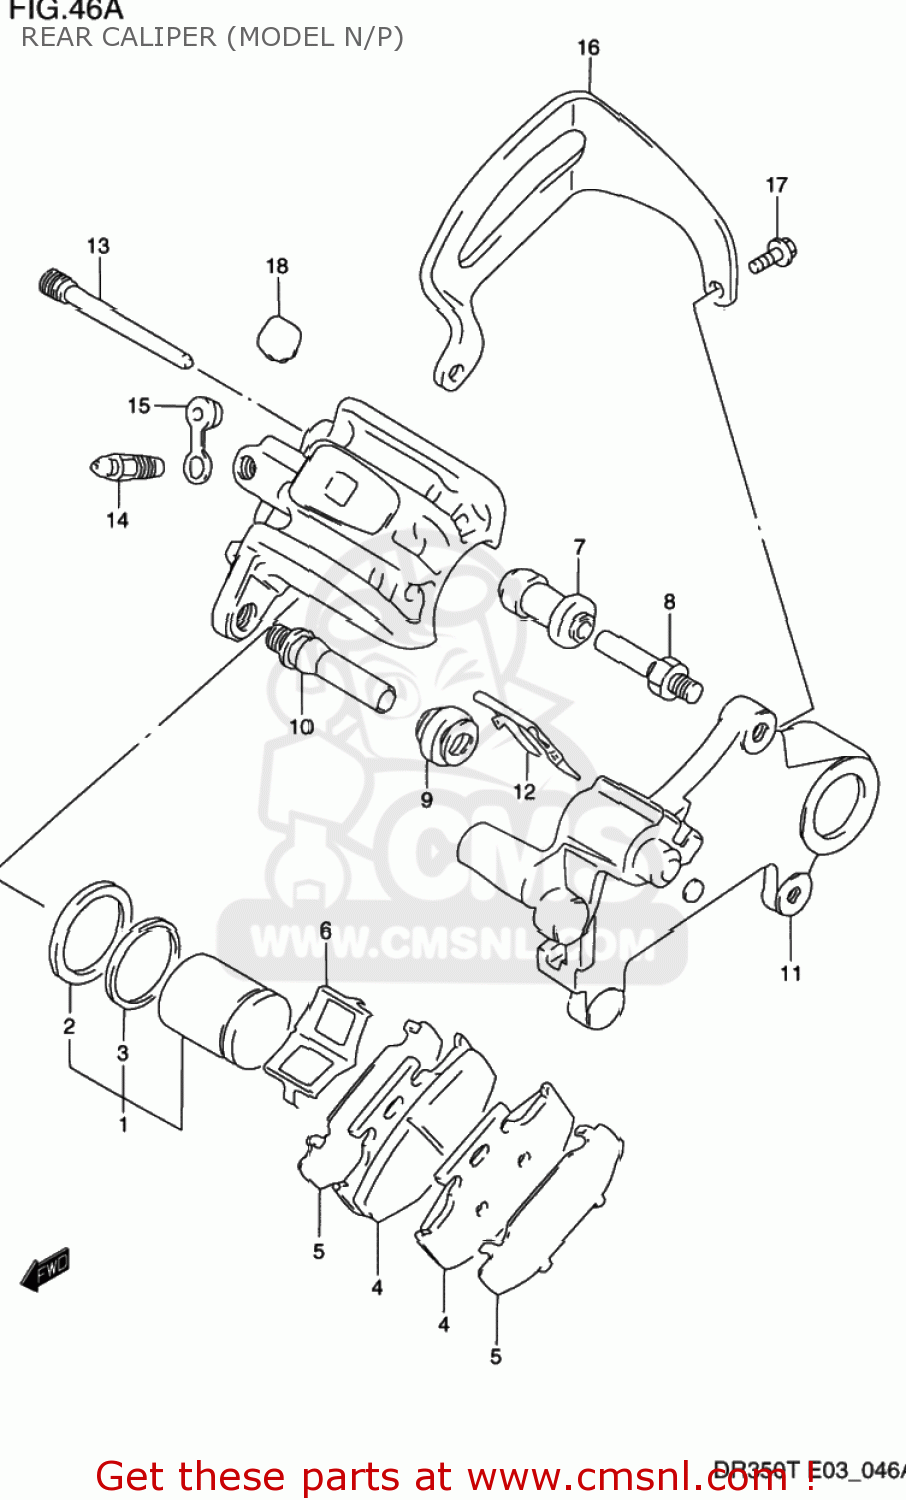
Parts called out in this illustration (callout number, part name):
1	PISTON SET
2	SEAL,PISTON
3	SEAL,DUST
4	PAD
5	SHIM
6	SPRING,PAD
7	BOOT
8	PIN,BOLT
9	BOOT
10	PIN
11	BRACKET
12	RETAINER,BRACKET
13	PIN,HANGER
14	BLEEDER
15	CAP,BLEEDER
16	GUARD,RR CALIPER
17	BOLT
18	COVER,RR CALIPER BODY
